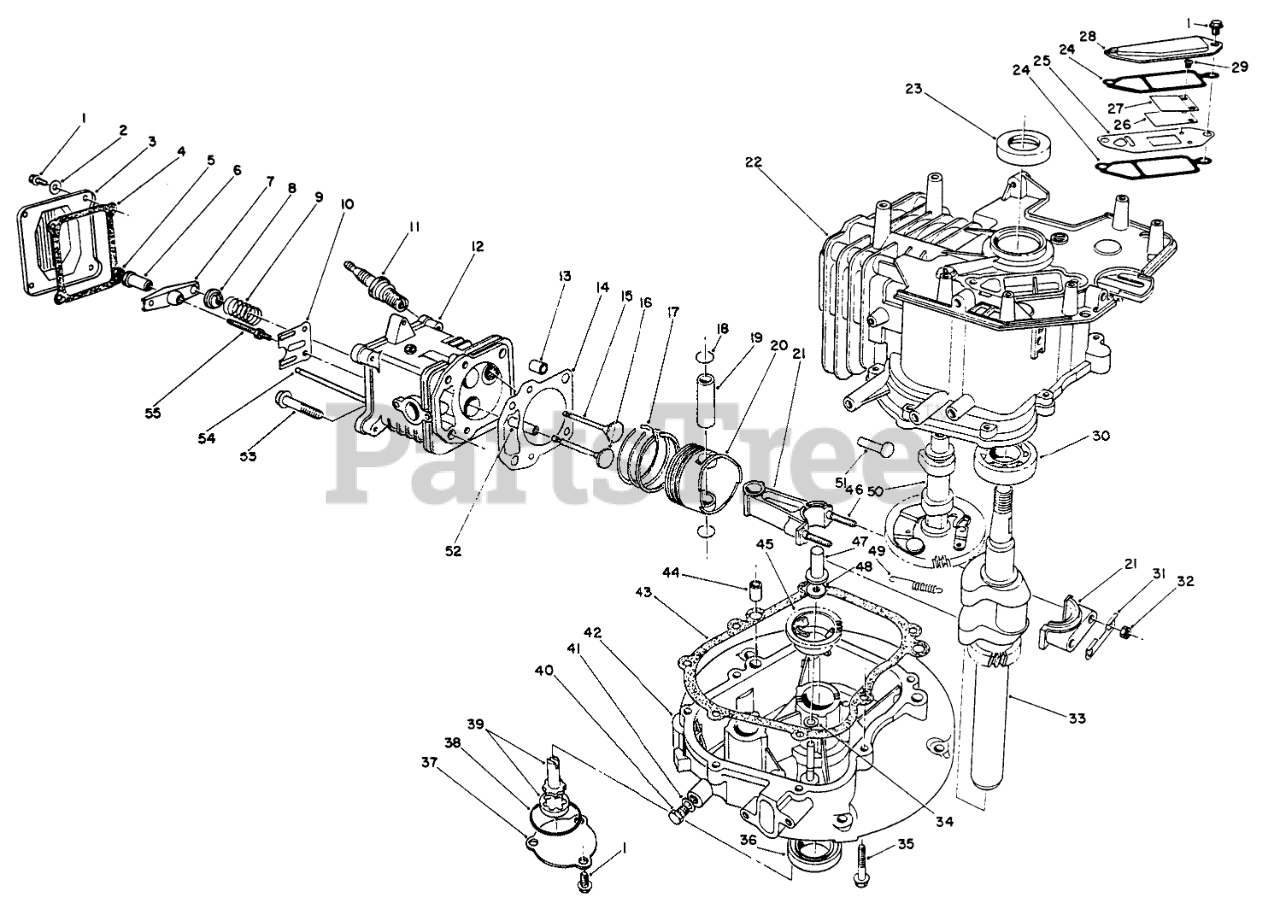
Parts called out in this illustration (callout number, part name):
2	WASHER
3	COVER
4	GASKET
6	PIVOT
8	RETAINER
9	SPRING
10	GUIDE
11	SPARK PLUG
12	Head-Cylinder (Incl. Ref. #52)
14	GASKET
15	VALVE-EXHAUST
16	VALVE-INTAKE
17	RING SET
18	CIRCLIP
20	PISTON
21	Connecting Rod Assembly (Incl. Ref. #31, 32 & 46)
22	Block-Engine (Incl. Ref. #23 & 30)
24	GASKET
25	Plate-Breather
26	Valve-Reed
27	Retainer-Reed Valve
28	COVER
29	Screw-Reed Valve
30	BEARING
31	Plate-Lock
33	CRANKSHAFT
34	WASHER
37	COVER
38	O-RING
39	OIL PUMP
40	OIL DRAIN PLUG
41	GASKET
42	Crankcase
43	GASKET
45	GOVERNOR FLYWEIGHT ASM
47	PLUNGER
48	WASHER
49	SPRING
50	Camshaft Assembly (Incl. Ref. #49)
51	TAPPET
52	GUIDE
